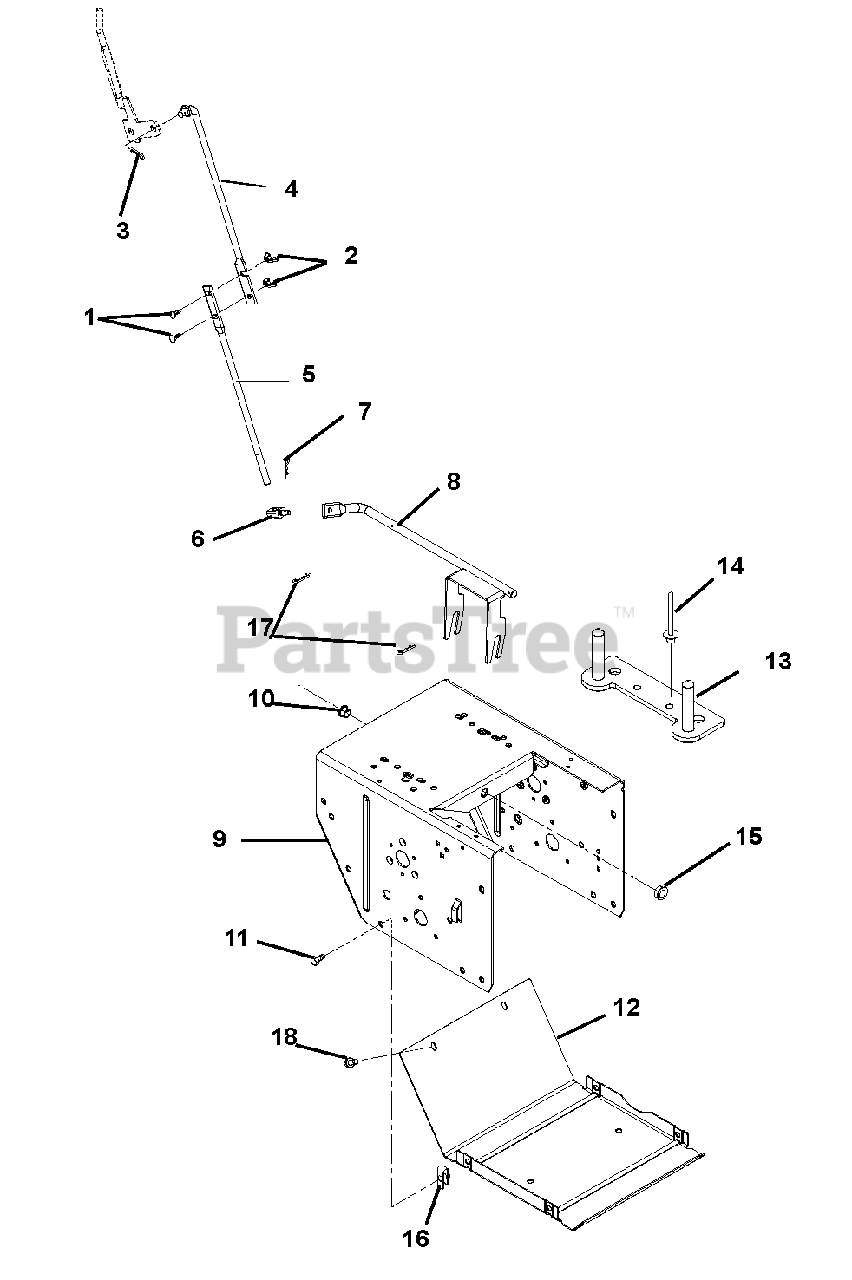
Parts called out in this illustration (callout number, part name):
1	@BLT-RDHDSQNK .25-20X1.00 G5YZ
2	NUT-LK WING .250-20 YWZC
3	PIN-HAIR, ENDRIES #25 YWZC
4	ROD, SHIFT-UPPER
5	ROD, SHIFT-LOWER
6	PIVOT,SHIFT ROD .375-16(TRUNN)
7	PIN-HAIR, ENDRIES #25 YWZC
8	ARM, SHIFT-WELDMENT
9	FRAME, MAIN
10	BUSHING, POLYLINER-.50 SPLIT
11	BLT-HEX .25-20X.75 HWH YZ GR5
12	COVER, BOTTOM
13	STRAP, ENGINE BOLT-WELDMENT
13	STRAP, ENGINE BOLT-LARGE BRIGG
14	RVT-POP .187 YZ
15	BUSHING, POLYLINER-.50 SNAPIN
16	NUT-RTNR .25-20X.56
17	CLIP, SPRING
18	@SCR-TAP .25-20X.50 HWH TR YWZ
